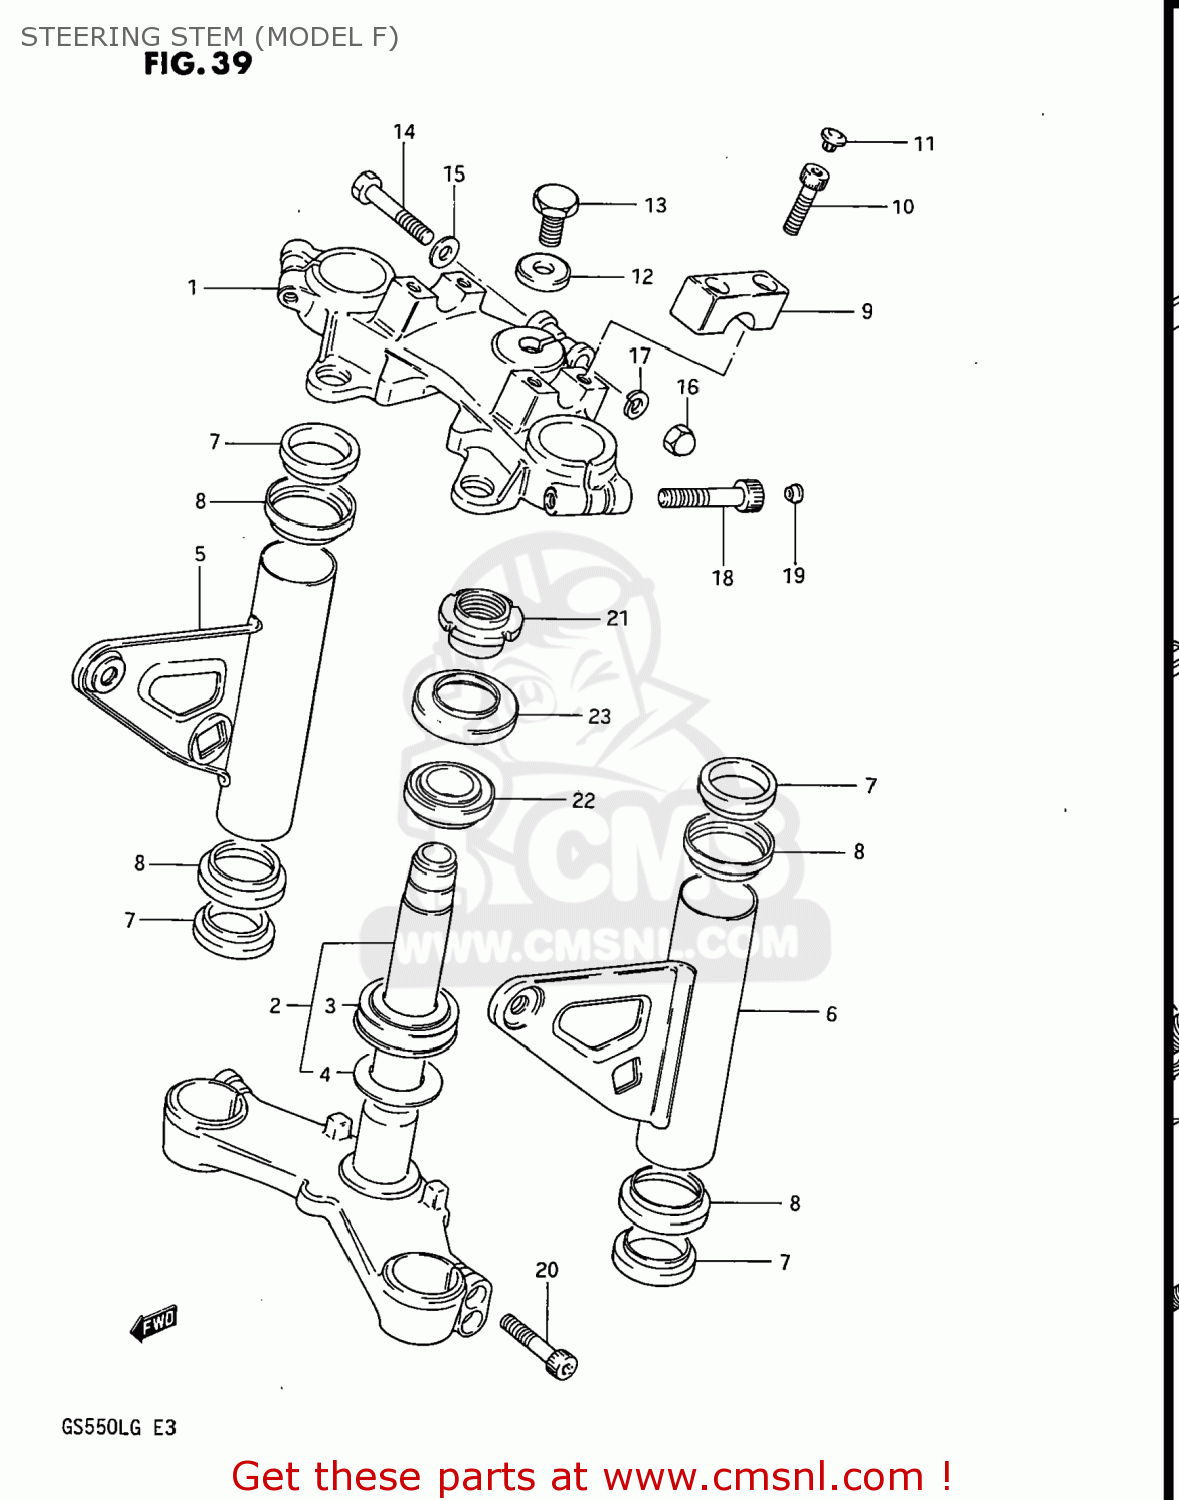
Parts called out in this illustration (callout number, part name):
1	HEAD,STEERING STEM
2	STEM,STEERING
3	BEARING
4	WASHER,THRUST
5	BRACKET,HEADLAMP,RIGHT
6	BRACKET,HEADLAMP,LEFT
7	CUSHION
8	CAP,HEADLAMP BRACKET
9	HOLDER,HANDLEBAR
10	BOUT
11	CAP(OD:14.5)
12	WASHER,STEERING STEM
13	BOLT,STEERING STEM HEAD
14	BOLT 8X50
15	WASHER
16	NUT
17	LOCK WASHER
18	BOLT, REAR
19	CAP(OD:20)
20	BOLT 8X35
21	NUT,STEERING STEM
22	TAPER,ROLLER BEARING
23	DUST SEAL,STEERING UPR
